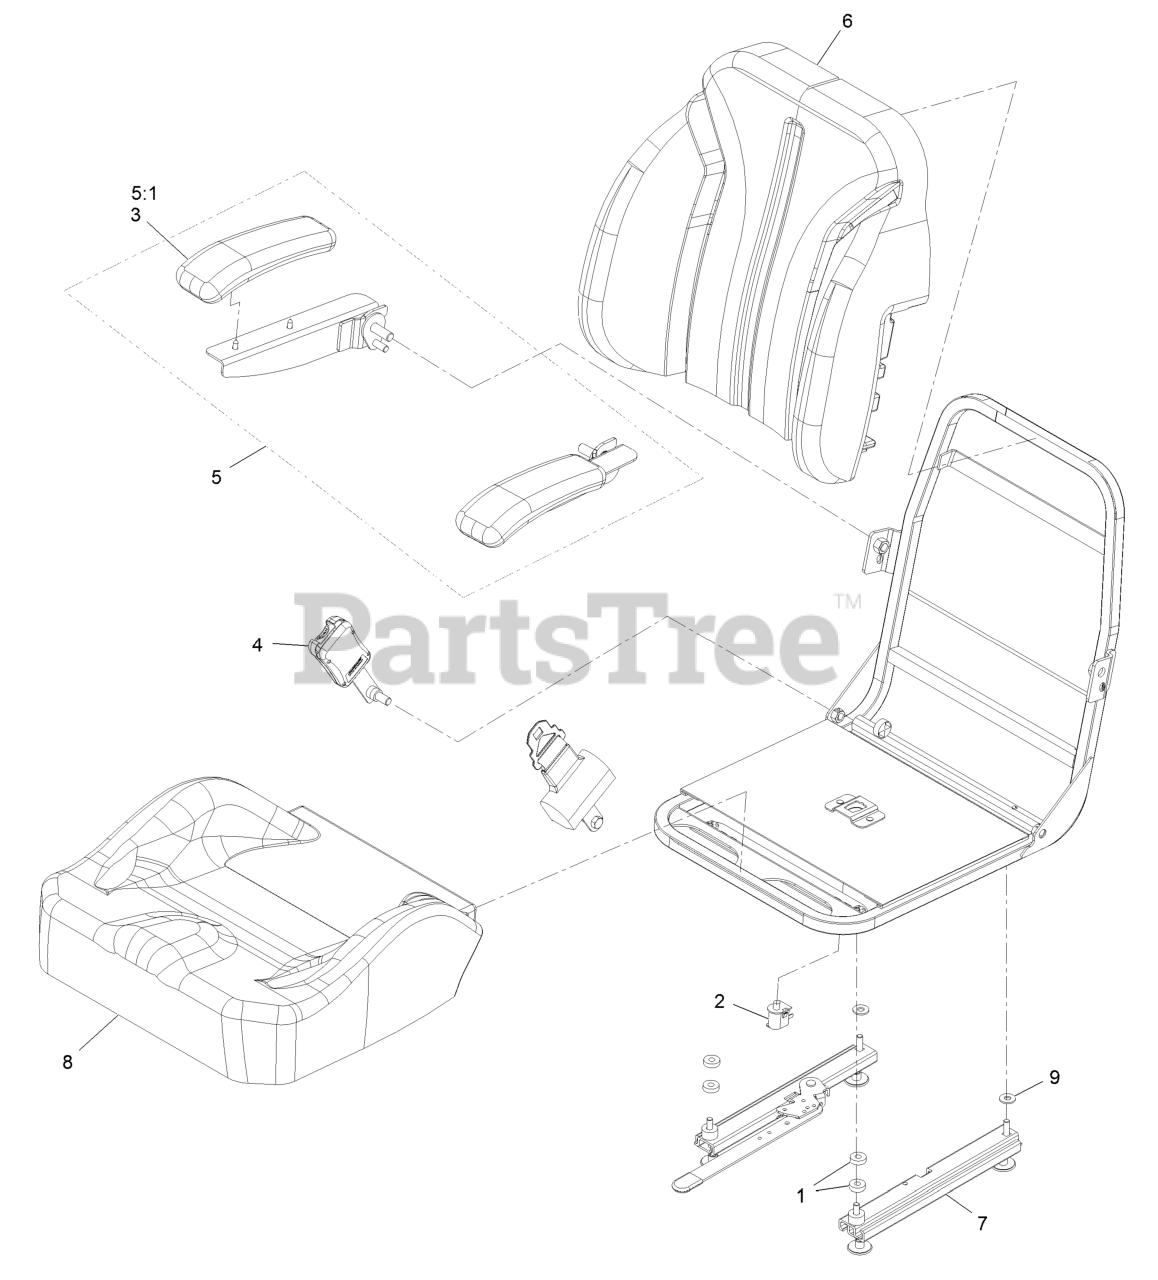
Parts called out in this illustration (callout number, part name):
2	SWITCH-BAIL
3	CUSHION-REST, ARM
4	SEAT BELT KIT
5	ARMREST KIT
5:1	CUSHION-REST, ARM
6	COVER-SEAT BACK SVC
7	TRACK-SEAT
8	COVER-SEAT BOTTOM SVC
9	WASHER-FLAT
